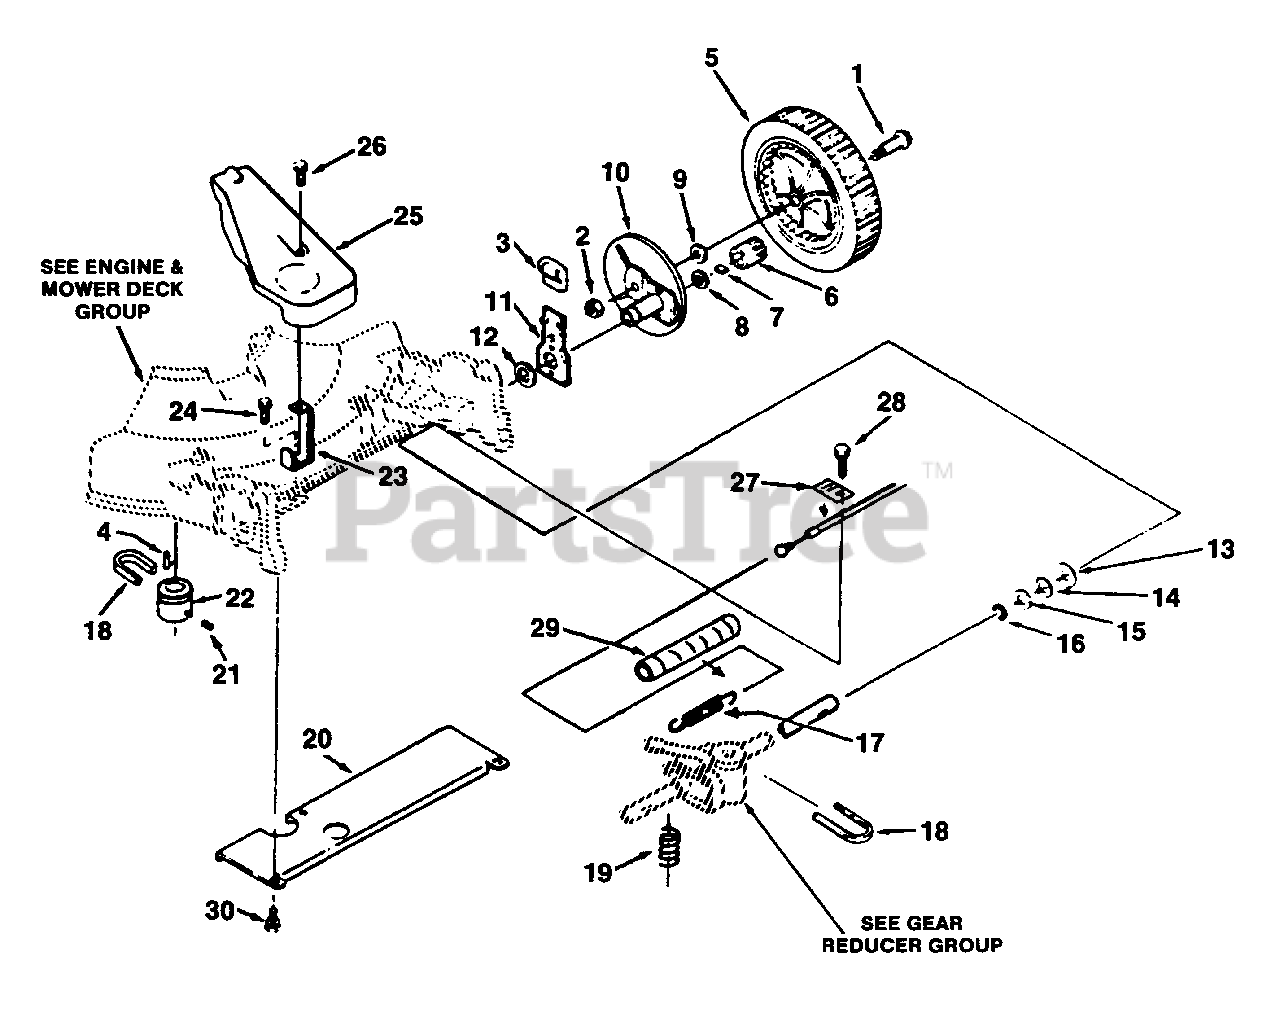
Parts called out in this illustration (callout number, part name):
2	NUT, Flange, 5/16-18
4	KEY
5	WHEEL & TIRE ASSY.
6	PINION, R.H.
6	PINION, L.H.
10	DRIVE WHEEL SUPPORT ASSY.
11	INDEXING SPRING & PIN ASSY.
15	WASHER, Shim
16	RING, Eaton
17	SPRING, Extension
18	BELT, Drive
19	SPRING, Compression
20	COVER, Rear
22	PULLEY, Drive
23	BRACKET, Gear Box Cover
24	SCREW, Sems Thd., 1/4-20 x 9/16"
25	COVER, Drive
26	SCREW, 1/4-20 x 3/4"
27	CLAMP, Cable
28	SCREW, 1/4-20 x 5/8"
29	COVER, Spring
30	SCREW, Hex Hd.,1/4-20 x 3/4
